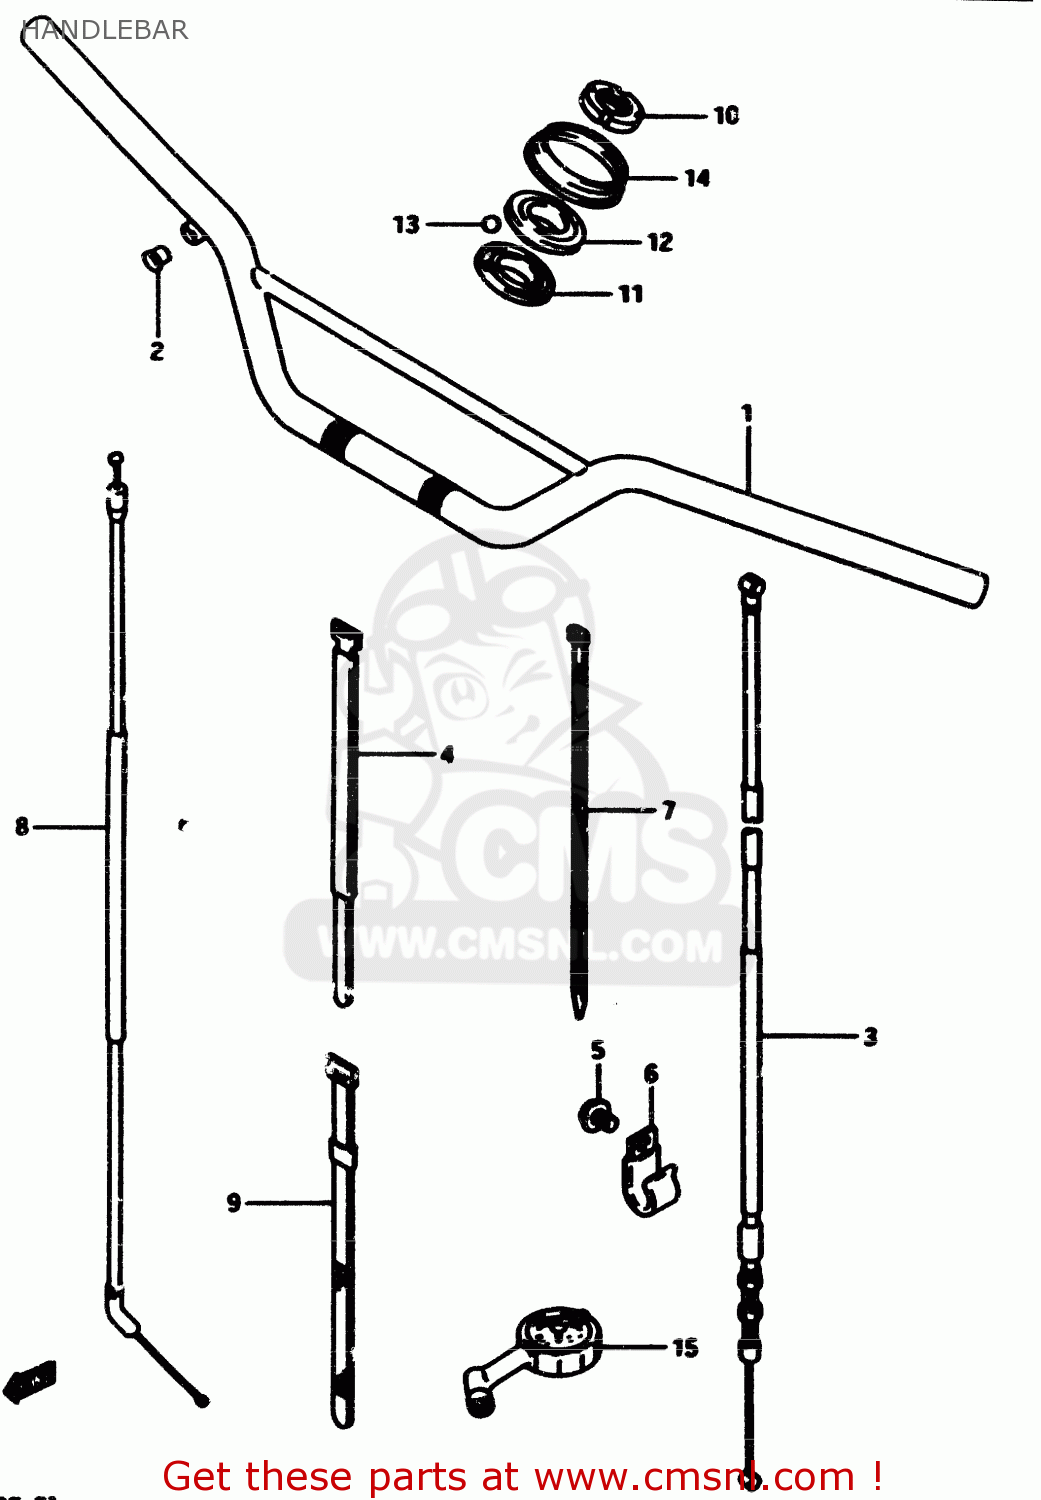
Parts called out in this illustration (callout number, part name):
1	HANDLEBAR (GOLD)
2	CAP(OD:14)
3	CABLE ASSY,CLUTCH
4	CLAMP
5	SCREW
6	CLAMP
7	CLAMP
8	CABLE ASSEMBLY,THROTTLE
9	CLAMP(L:187)
10	NUT,STEERING STEM
11	RACE,STEERING,INNER,UPPER
12	RACE,STEERING,OUTER,UPPER
13	BALL
14	SEAL,STEERING UPR DUST
15	GAUGE ASSY,AIR PRESSURE
